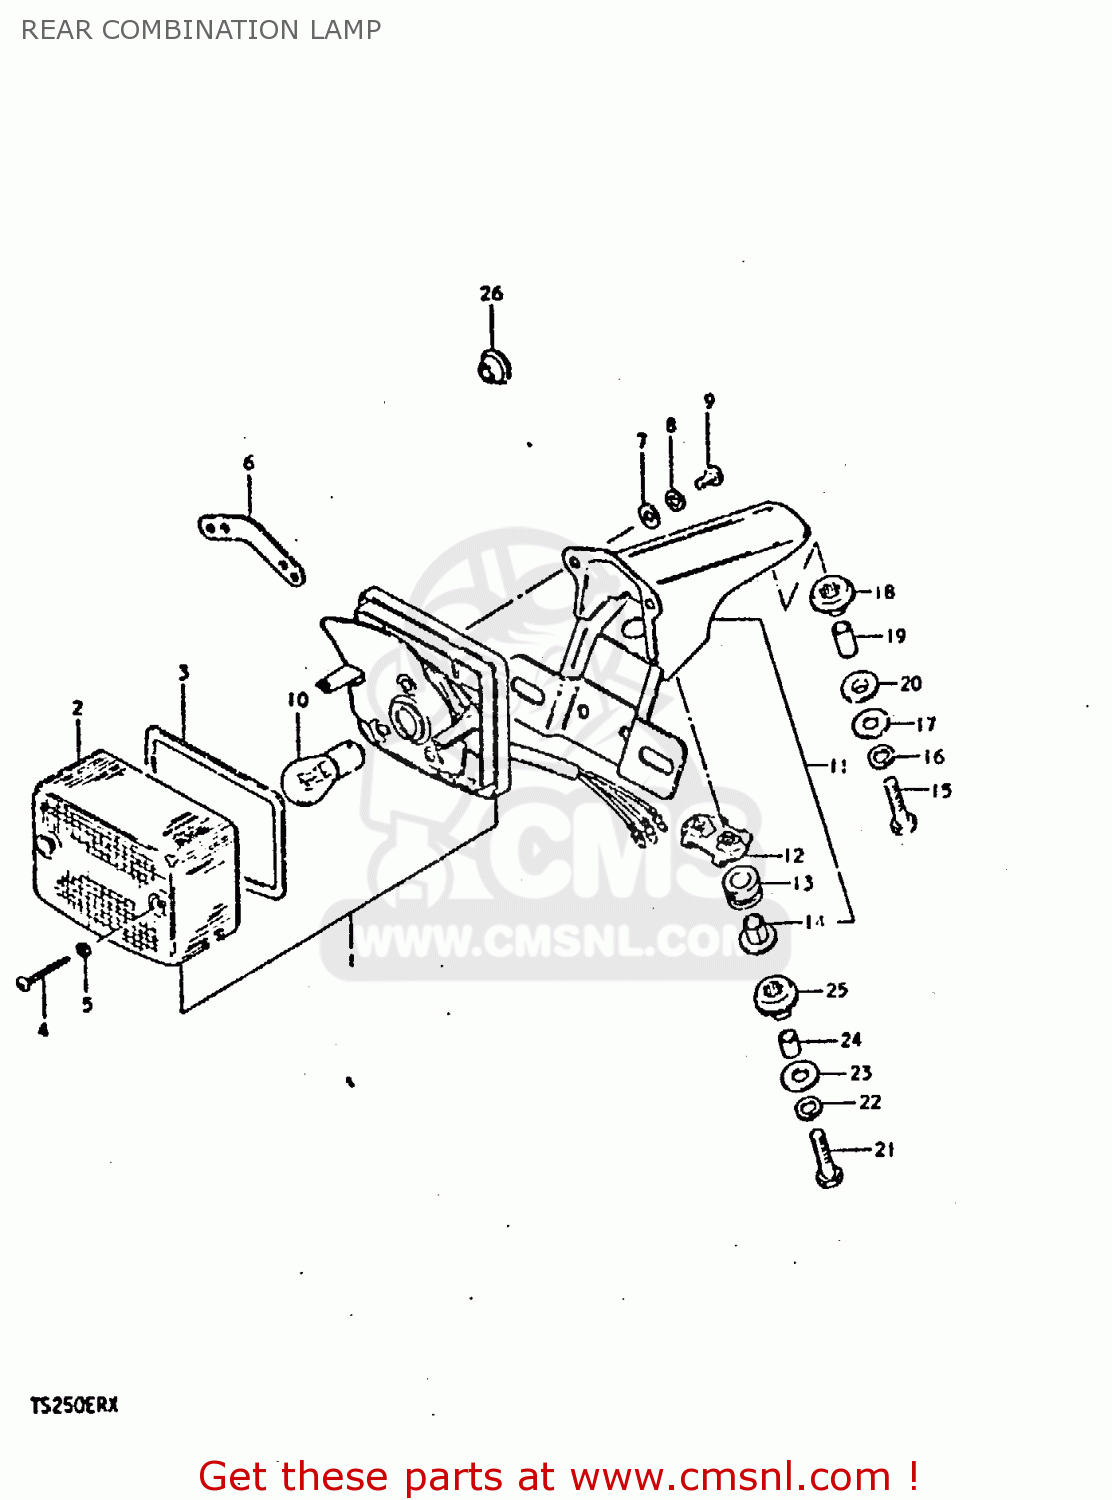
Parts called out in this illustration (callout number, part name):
1	LAMP UNIT,REAR COMBINATION
2	LENS
3	GASKET (NAS)
4	BOLT
5	GASKET (NAS)
6	PLATE,REAR COMBINATION LAMP
7	WASHER
8	LOCK WASHER
9	SCREW
10	BULB(6V32/3CP,STANLEY)
11	BRACKET UNIT,TAIL LAMP
12	PLATE
13	CUSHION
14	SPACER
15	BOLT
16	LOCK WASHER
17	WASHER (6.5X20X1.2)
18	CUSHION
19	SPACER
20	CUSHION
21	BOLT 8X45
22	LOCK WASHER
23	WASHER (6.5X20X1.2)
24	SPACER
25	CUSHION
26	GROMMET
